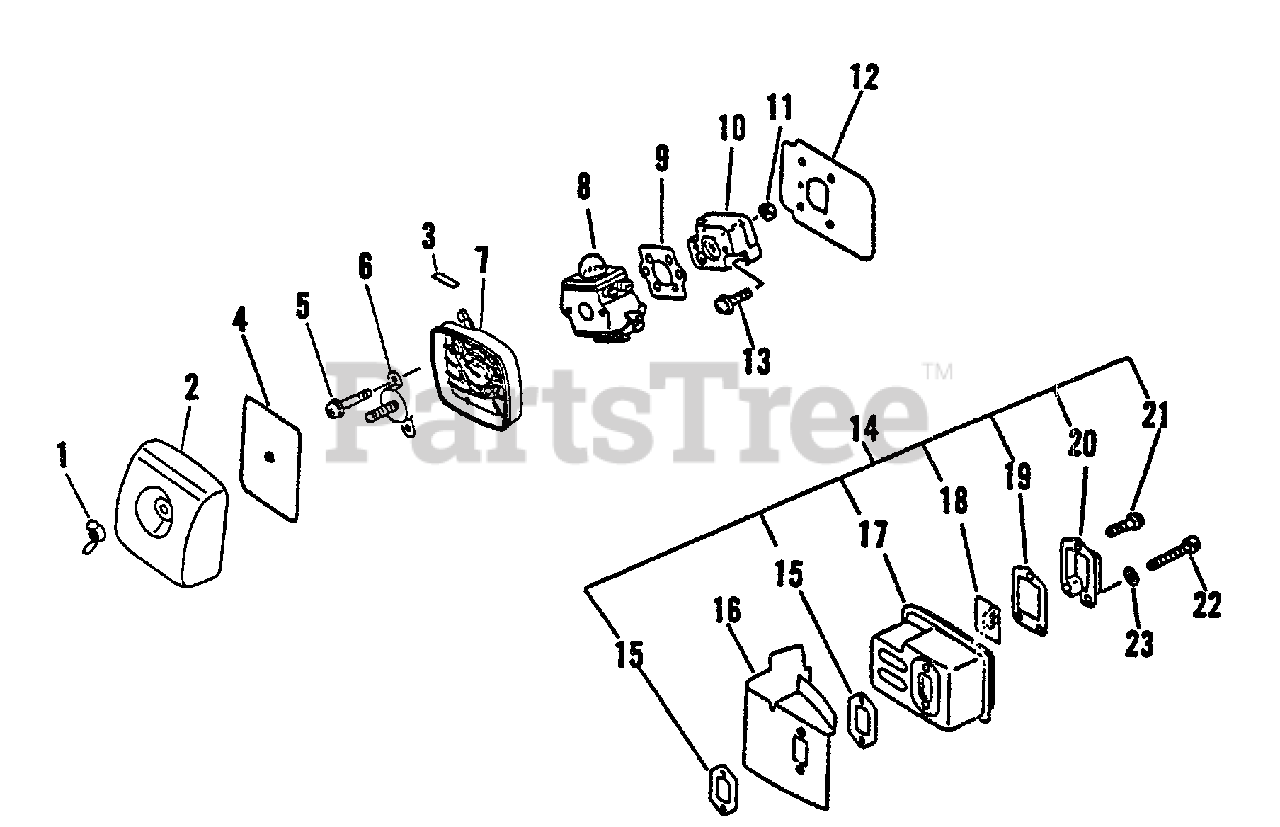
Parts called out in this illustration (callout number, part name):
1	WINGNUT - 6
2	COVER, AIR FILTER - BLACK
3	LABEL, CHOKE
4	FILTER, AIR
5	SCREW 5×65
6	PLATE, PREVENT
7	CASE ASSY, AIR FILTER
8	CARBURETOR - C1U-K27B
9	GASKET, INTAKE
10	INSULATOR, INTAKE
11	NUT M5
12	HEAT SHIELD, INTAKE
13	SCREW 5×20
14	MUFFLER ASSY
15	GASKET, EXHAUST
16	COVER, MUFFLER
18	SCREEN, SPARK ARRESTER
19	GASKET, EXHAUST
20	GUIDE, EXHAUST - INNER
21	SCREW 4×10
22	BOLT M5×50
23	WASHER, FLAT 5.5×10×0.8
